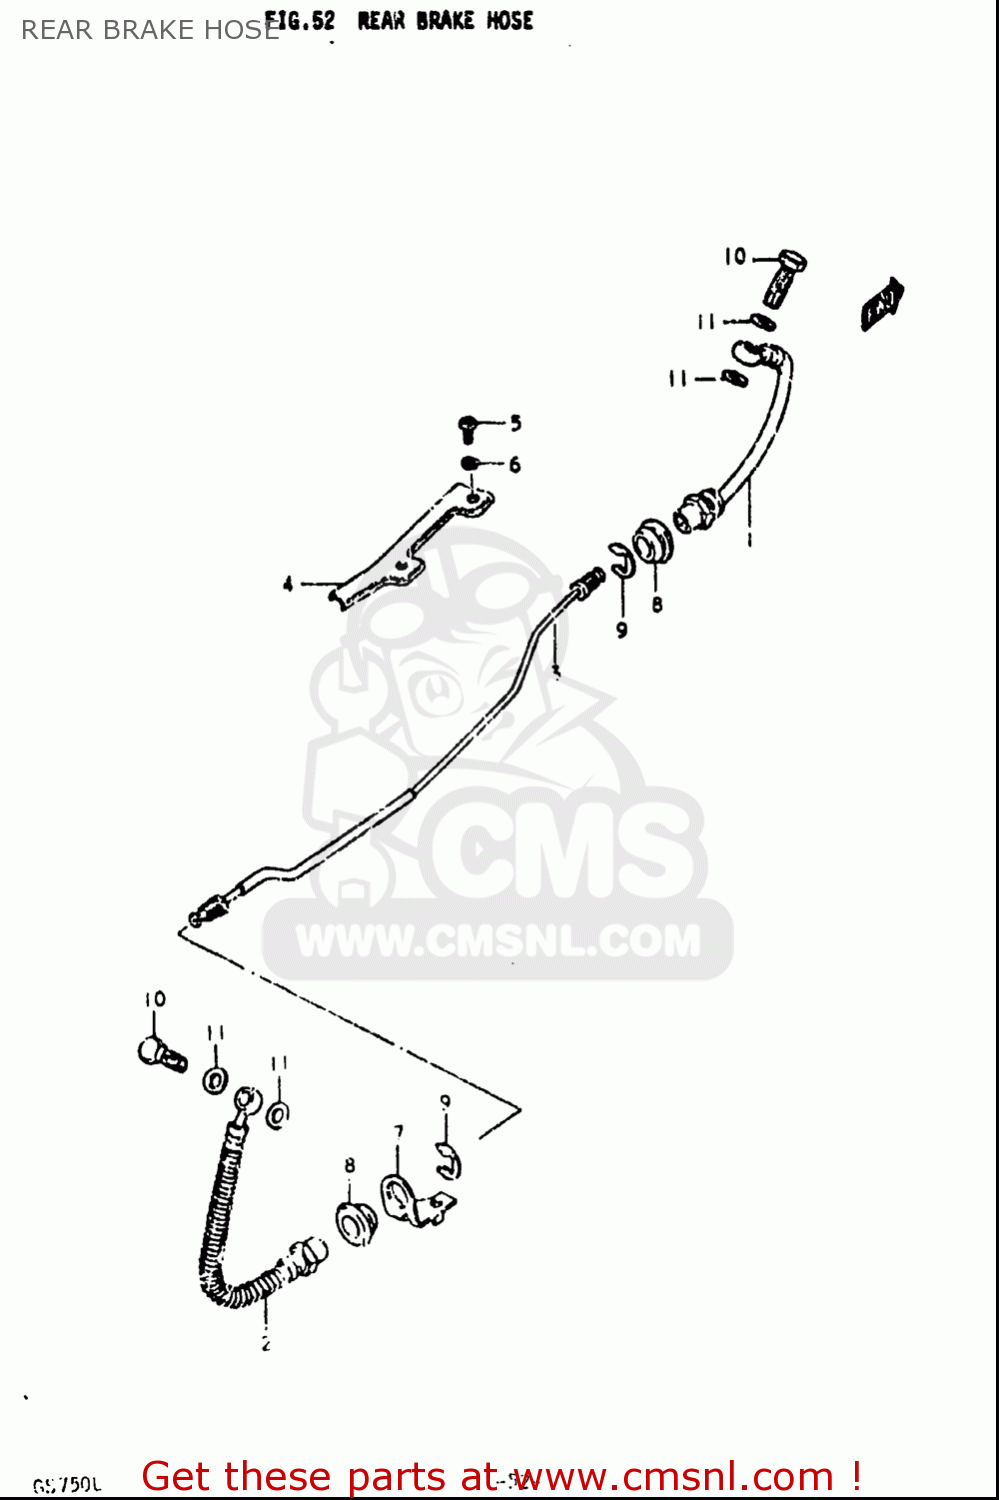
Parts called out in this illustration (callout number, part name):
1	HOSE,RR BRAKE NO.2
2	HOSE,RR BRAKE NO.2
4	COVER,REAR BRAKE PIPE
5	BOLT(6X8)
6	WASHER,LOCK
7	GUIDE,BRAKE HOSE
8	GROMMET,BRAKE HOSE GUIDE
9	E RING
10	BOLT UNION
11	WASHER(10X15X1.5)
